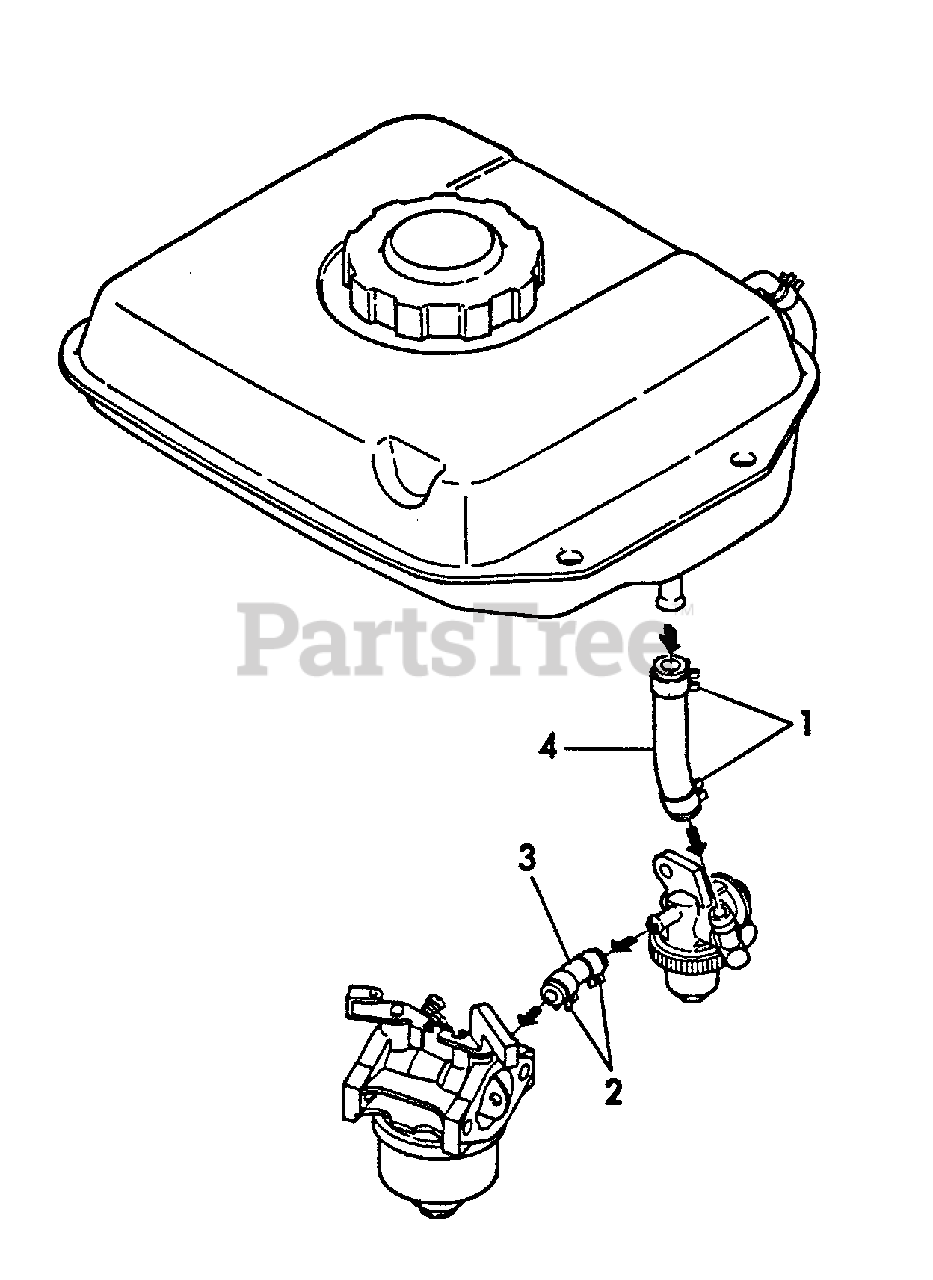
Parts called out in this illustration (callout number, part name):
1	CLAMP, HOSE
2	CLAMP, HOSE - 9
3	PIPE - FUEL
4	PIPE - FUEL
